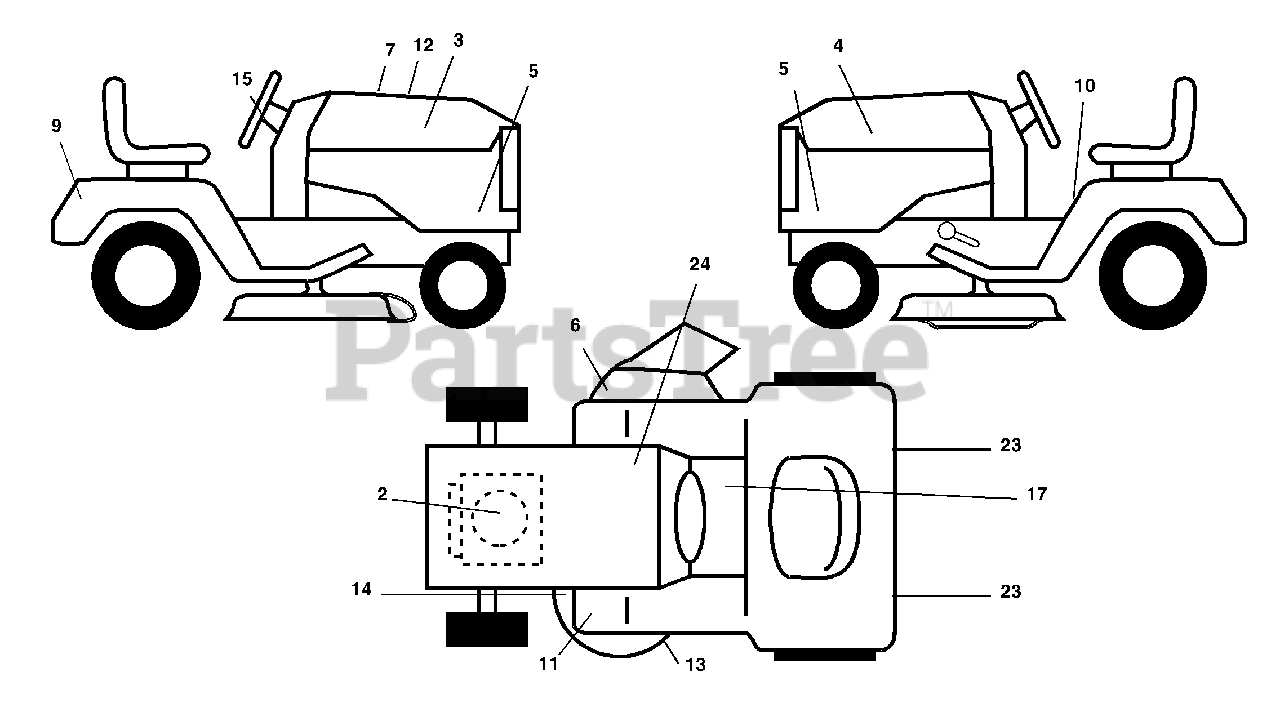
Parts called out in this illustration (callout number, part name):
2	Decal, Engine
3	Decal, Hood, RH
4	Decal, Hood, LH
5	Decal, Side Panel
6	Decal, Warning
7	Decal, Customer Resp.
9	Decal, Fender
10	Decal, Danger
11	Decal, Foot Rest
12	Decal, Final
13	Decal, V-Belt Sch
14	Decal, Caution
15	Decal, Ins. Strg Whl
17	Decal, Saddle Brake Parking
23	Reflector, Taillight
24	Decal, Btry Dngr/Psn
24	Decal, Bypass
24	Decal, Handle Lift (Lift Handle)
